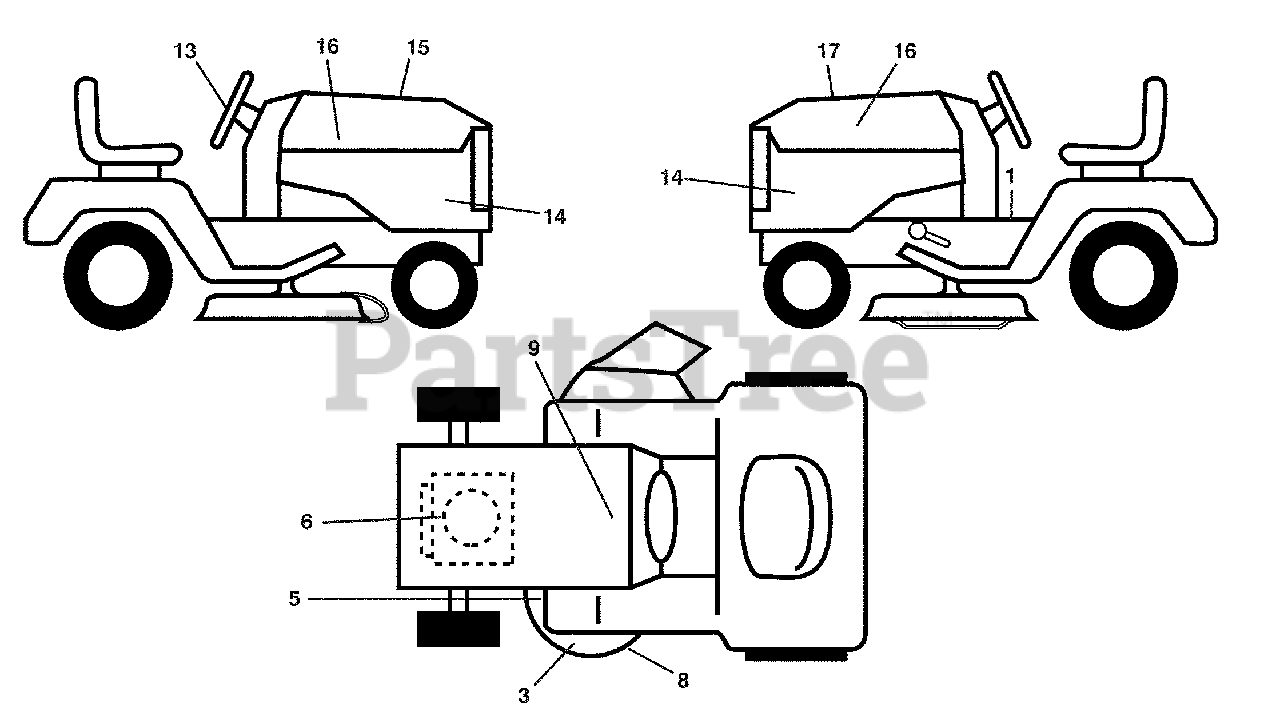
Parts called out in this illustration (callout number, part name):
1	Decal, Fender Warning
3	Decal, Warning
5	Decal, Caution
6	Decal, Eng. HP
8	Decal, Mower Sch.
9	Decal, Battery Dnge/Poi
13	Decal, Steering Whl
14	Decal, Panel Side
15	Decal, Cust. Resp.
16	Decal, Hood Logo
17	Decal, Replacement
